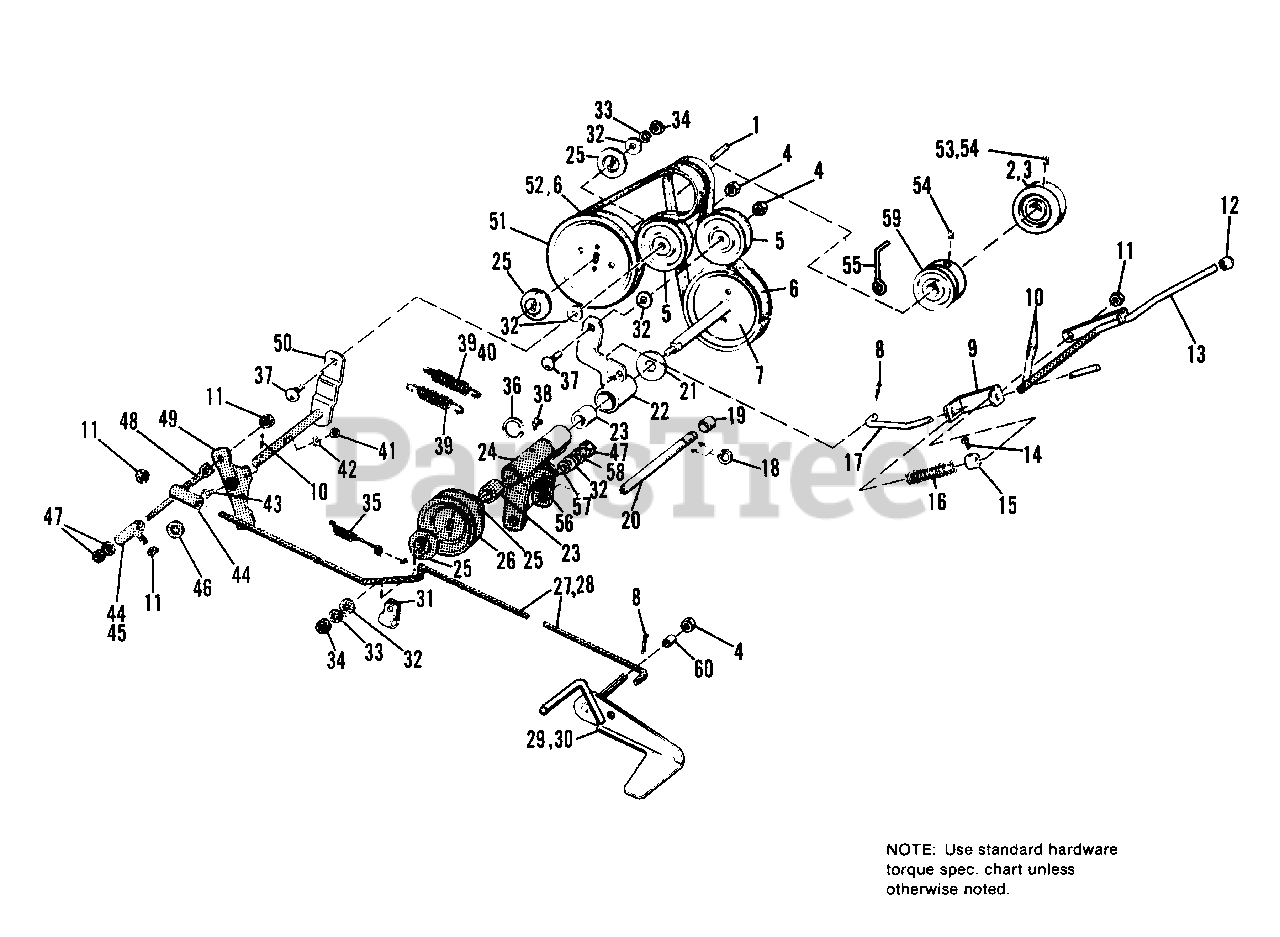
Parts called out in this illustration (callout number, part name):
1	KEY
2	PULLEY, Engine
3	PULLEY, Engine
4	LOCKNUT, Hex, 3/8-16
5	PULLEY, Idler
6	BELT, V (Qty. 1 used on 990357 Only)
7	PULLEY & SHAFT ASSY.
8	PIN, Cotter, 3/32 x 3/4
9	GUIDE ASSY., Rod
10	PIN, Cotter, 1/8 x 1
11	LOCKNUT, Hex, 5/16-18
13	HANDLE ASSY., PTO Control
14	SETSCREW, 1/4-20 x 3/8
15	COLLAR, Set
17	ROD, Clutch, PTO
18	RING, Retaining
20	SHAFT, Pivot
22	LEVER ASSY., Idler
23	BEARING, Needle
24	HOUSING ASSY.
25	WASHER, Special
26	PULLEY, Mower Drive
27	ROD, Clutch
28	ROD, Clutch
29	PEDAL ASSY., Foot
30	PEDAL ASSY., Foot
32	WASHER, Plain, 5/16
33	LOCKWASHER, 3/8
34	NUT, Hex, Full, 3/8-16
35	SPRING, Clutch Rod
36	RING, Retaining
37	BOLT, Carriage, 3/8-16 x 1
38	FITTING, Grease
39	SPRING (Qty. 1 used on 990391 Only)
40	SPRING
41	NUT, Hex, Full, 1/4-20
42	LOCKWASHER, 1/4
43	CAPSCREW, Hex Hd., 1/4-20 x 1-1/4
44	GUIDE ASSY., Rod (Qty. 1 used on 990391 Only)
45	GUIDE ASSY., Rod
46	WASHER, Plain, 7/16
47	NUT, Hex, Full, 5/16-18 (Qty. 2 used on 990357 Only)
48	ROD, Brake
50	ARM ASSY., Idler Pulley
51	PULLEY, Transmission
52	BELT, V
53	SETSCREW, 5/16-18 x 1/2
54	SETSCREW, 5/16-18 x 5/16
55	STOP, Belt
56	CAPSCREW, Hex Hd., 5/16-18 x 7/8
57	STOP, Belt
58	LOCKWASHER, 5/16
59	PULLEY, Half
